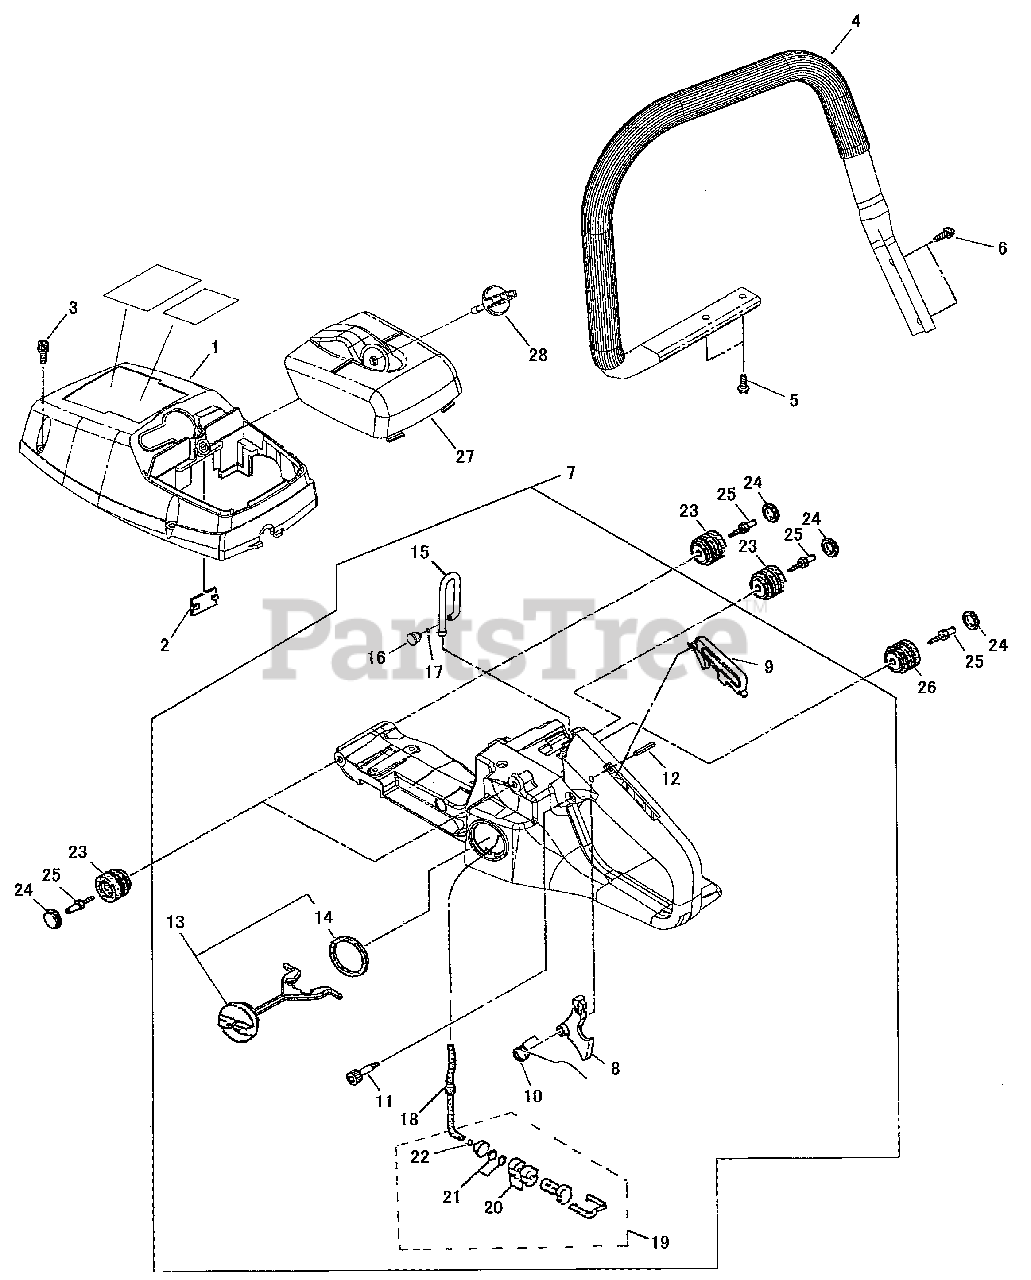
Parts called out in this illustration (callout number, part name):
1	COVER, ENGINE
2	PLUG
3	BOLT
4	HANDLE - FRONT
5	SCREW
6	SCREW - 5X20
7	HANDLE ASSY - REAR
8	TRIGGER, THROTTLE
9	LEVER, LOCK
10	LEVER, SPRING
11	BOLT
12	PIN - 4X25
13	CAP ASSY
14	GASKET, CAP
16	ELEMENT, BREATHER
17	RING, RETAINING - 6
18	PIPE - FUEL
19	FILTER, FUEL
20	FILTER, FUEL
21	SCREEN, FILTER
22	RING, RETAINING - 6
23	CUSHION
24	SEAL, DUST
25	BOLT
26	CUSHION
27	COVER, AIR FILTER
28	KNOB
